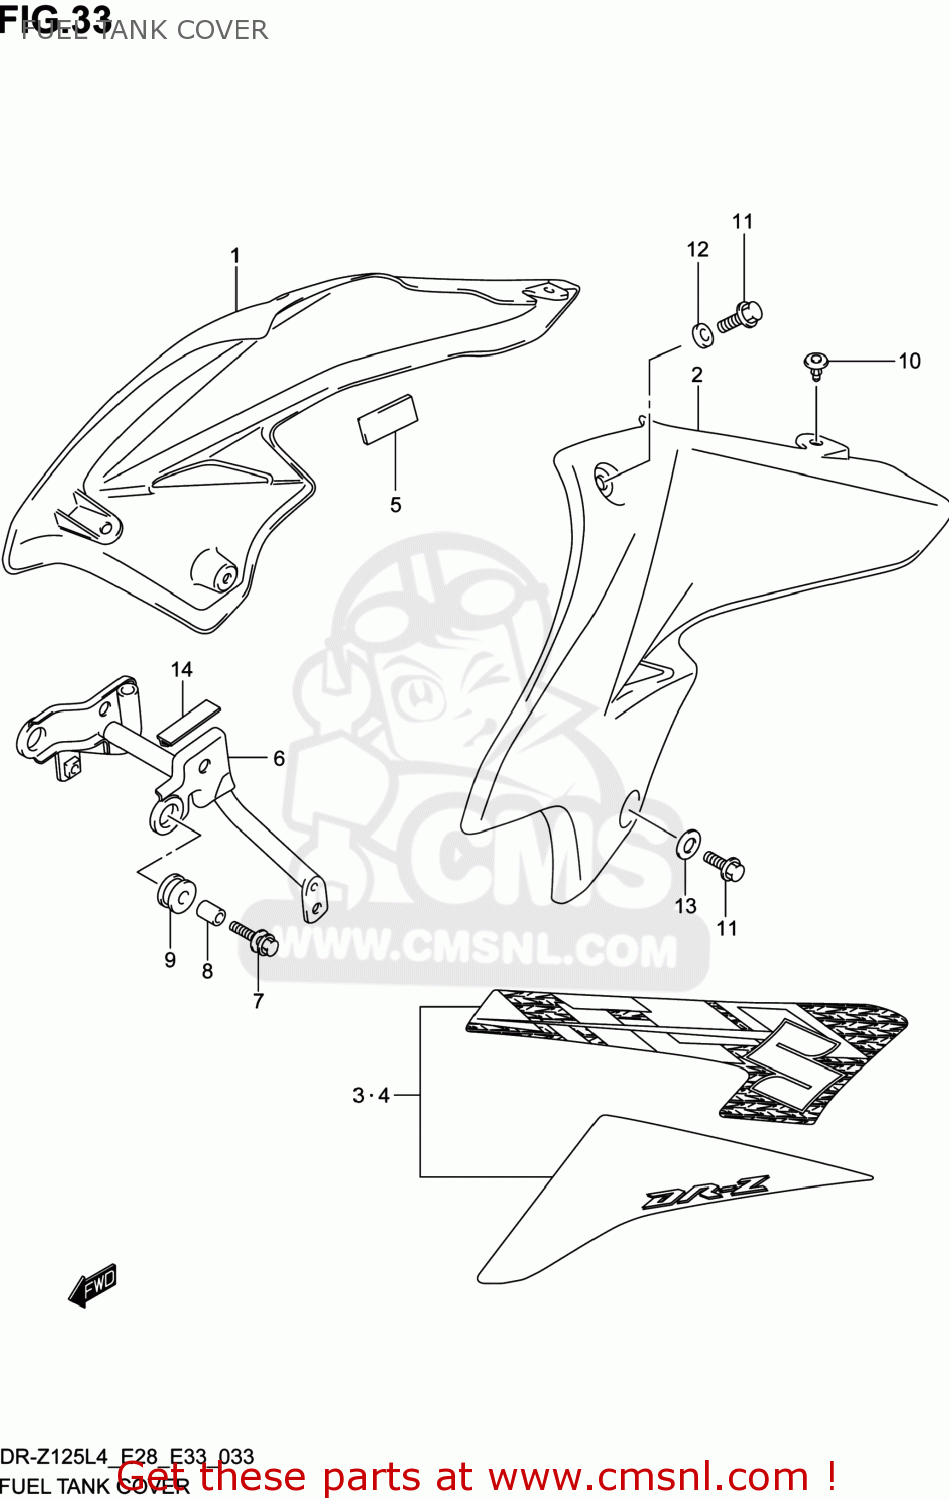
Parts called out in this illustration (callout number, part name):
1	COVER,FUEL TANK,R
2	COVER,FUEL TANK,L
3	TAPE SET,FUEL TANK COVER,R
4	TAPE SET,FUEL TANK COVER,L
5	CUSHION,FUEL TANK COVER
6	BRACKET,FUEL TANK FR
7	BOLT(6X25)
8	SPACER(6.5X9X13.5)
9	CUSHION,FUEL TANK SIDE
10	CLIP(BLACK)
11	BOLT
12	WASHER
13	WASHER
14	MOLDING
